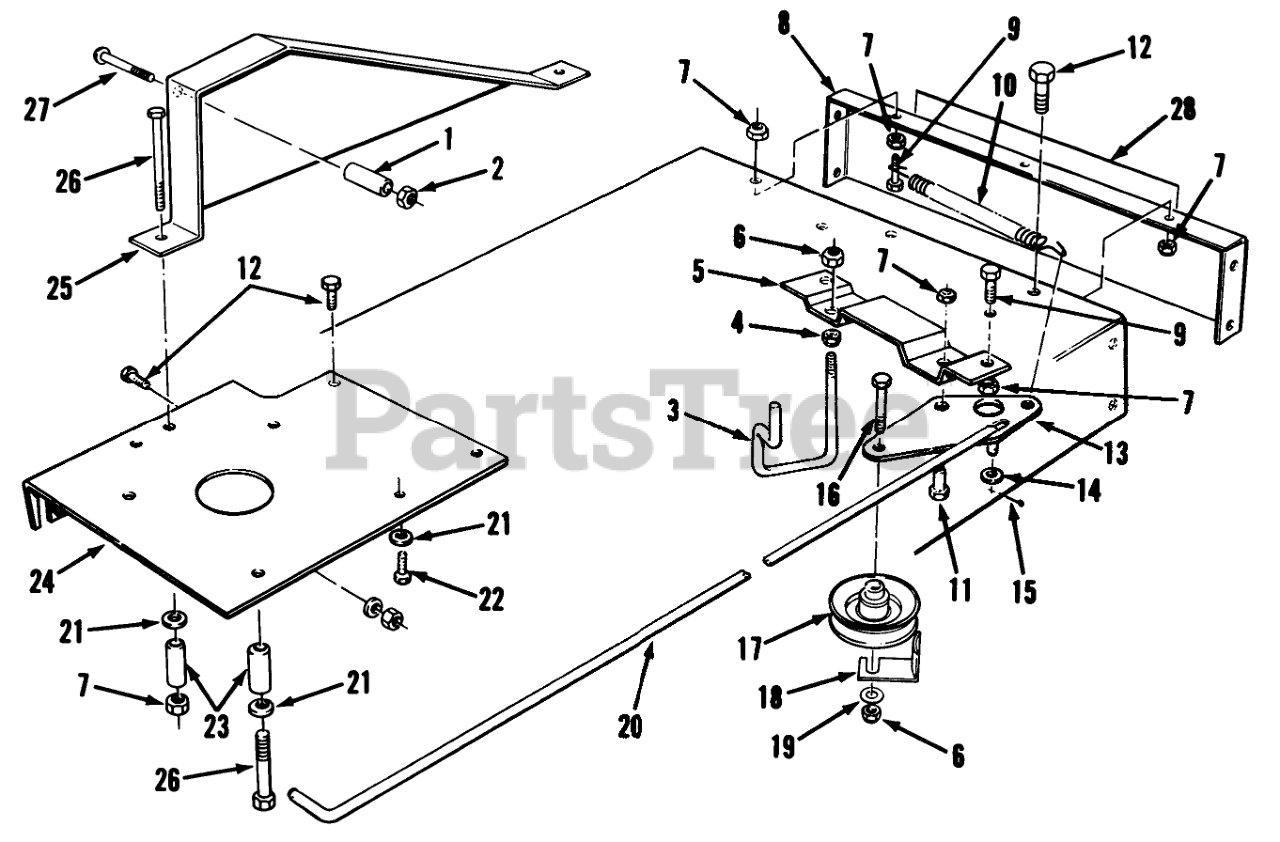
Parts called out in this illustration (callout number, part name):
1	FRONT CHAIN RETAINER
2	NUT-LOCK, NI
3	BELT GUIDE
4	NUT-LOCK, SIDE
5	TRACT SUPP BRKT B
6	NUT-LOCK, CONE
7	NUT-LOCK, NI
8	Frame-Rear
9	SCREW-HH
10	TRACTION SPRING
11	BOLT-SHOULDER
12	SCREW-HH
13	TRACTION PIVOT BRKT
14	WASHER-FLAT
15	PIN-COTTER
16	SCREW-HH
17	PULLEY-IDLER
18	RETAINER-BELT
19	WASHER-FLAT
20	TRACTION ROD
21	WASHER-PLAIN
22	Screw-HH
23	OUTER TUBE SPACER
24	REINF PLATE R
25	CHAIN GUARD R
26	SCREW-HH
27	SCREW-HH
28	DECAL - REAR FRAME
